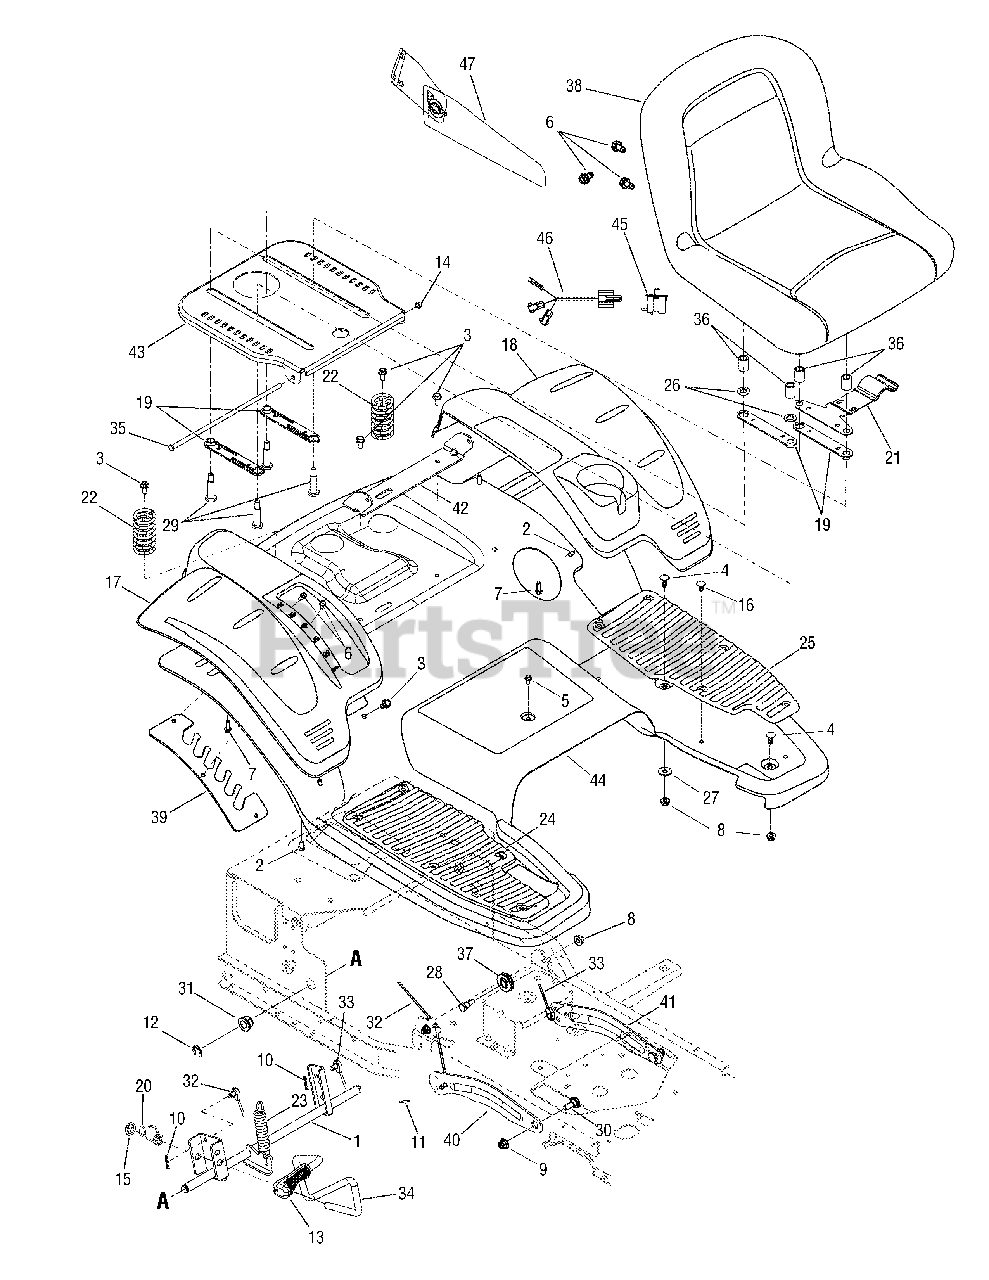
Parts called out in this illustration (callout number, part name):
1	Shaft, Lift
2	Screw, Hex Wash Hd. H/L, 1/4-15 x .5
3	Screw, Hex Wash Hd. Tapp, 5/16-18 x .75
4	Screw, Carriage, 5/16-18 x 75
5	Screw, Hex Wash Hd. Tapp, 1/4-20 x .5
6	Screw, Hex Wash Hd. Tapp, 5/16-18 x .75
7	Screw, Hex Wash Hd. Tapp, 1/4-15 x .75
8	Nut, Hex Flange Insert Lock, 5/16-18 GrF
9	Nut, Hex Flange Insert Lock, 3/8-16 GrF
10	Pin, Internal Cotter
11	Pin, Cotter, 3/32 x 1.0
12	E-ring, .625 Shaft
13	Grip, Handle
14	Nut, Speed, .3125 Dia.
15	Nut, Speed, .5
16	Clip, Ratchet
17	Cover, Rear Fender RH
18	Cover, Rear Fender LH
19	Spacer, Seat Adjust
20	Spring, Lift Handle Torsion
21	Spring, Seat Adjust
22	Spring, Compression, 1.71 x 3.25 x .23
23	Spring, Extension, .865 x 4.68
24	Pad, Foot RH
25	Pad, Foot LH
26	Washer, Flat, .535 x .93 x .09
27	Washer, Flat, .344 x 1.0 x .063 HT
28	Bolt, Shoulder, .496 x 2.5:3/8-16
29	Bolt, Shoulder, .496 x 1.525:3/8-16
30	Bolt, Shoulder, .625 x .175:3/8-16
31	Bearing, Hex Flange,
32	Cable, Lift, 16.64 Lg
33	Cable, Lift, 16.64 Lg
34	Handle, Lift
35	Rod, Seat, 5/16 x 11.62
36	Spacer, .51 x .75 x 1.0
37	Pulley, Roller
38	Seat, High Back
39	Plate, Deck Lift Index
40	Arm, Deck Lift RH
41	Arm, Deck Lift LH
42	Bracket, Seat Pivot
43	Plate, Seat Mounting
44	Fender, Rear
45	Switch, Seat
46	Harness, Seat Switch Jumper
47	Arm Rest, Seat
